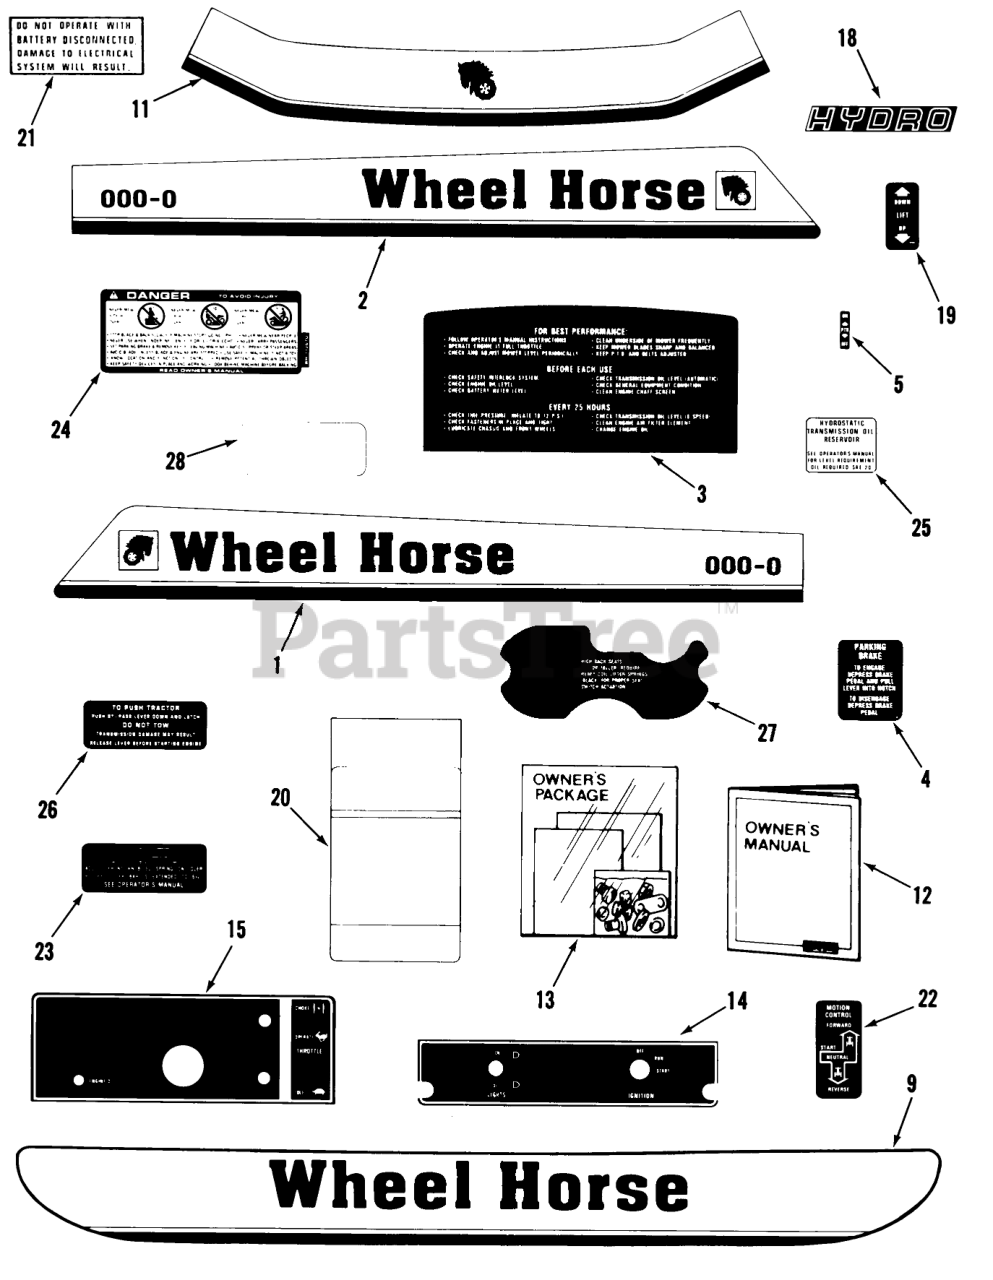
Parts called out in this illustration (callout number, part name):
1	DECAL-HOOD R.H.
2	DECAL-HOOD L.H.
3	DECAL-REAR HOOD
4	DECAL-PARKING, BRAKE
5	DECAL-PTO
9	DECAL-FENDER
11	DECAL-FRONT HOOD
12	Owner-s Manual-Tractor
13	New Tractor Loose Parts Package 252-H
13	New Tractor Loose Parts Package 257-H
14	DECAL BACK PLATE
15	Decal-Dash 252-H
15	DECAL-LOWER DASH
18	DECAL-HYDRO
19	DECAL-LIFT
20	Decal-Maintenance
21	DECAL ELECT SYSTEM
22	DECAL-SPEED CONTROL
23	DECAL-PTO BELT ADJ
24	DECAL-DANGER
25	DECAL-TRANS OIL
26	DECAL-TO PUSH TRAC
27	DECAL-SEAT LIFTER
28	DECAL-OVERLAY
